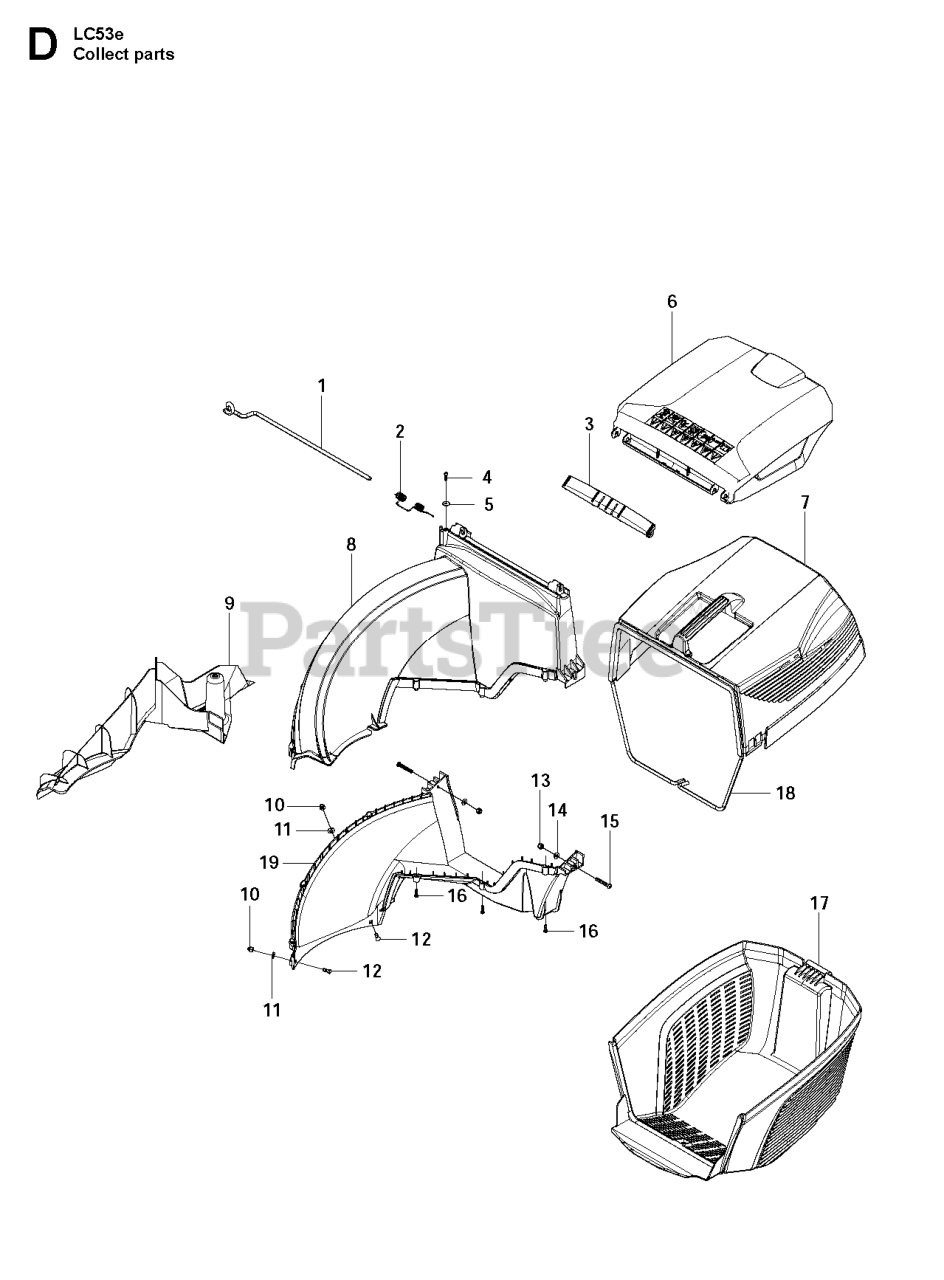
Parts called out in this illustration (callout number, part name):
1	AXLE HATCH REAR DISCHARGE
2	SPRING SAFETY FLAP A009
4	SCREW ITXPANT T50X16 ZN/FE (A
6	HATCH REAR DISCHARGE
7	GRASSBAG UPPER
16	SCREW ITXPANT T50X16 ZN/FE (A
17	GRASSBAG LOWER
